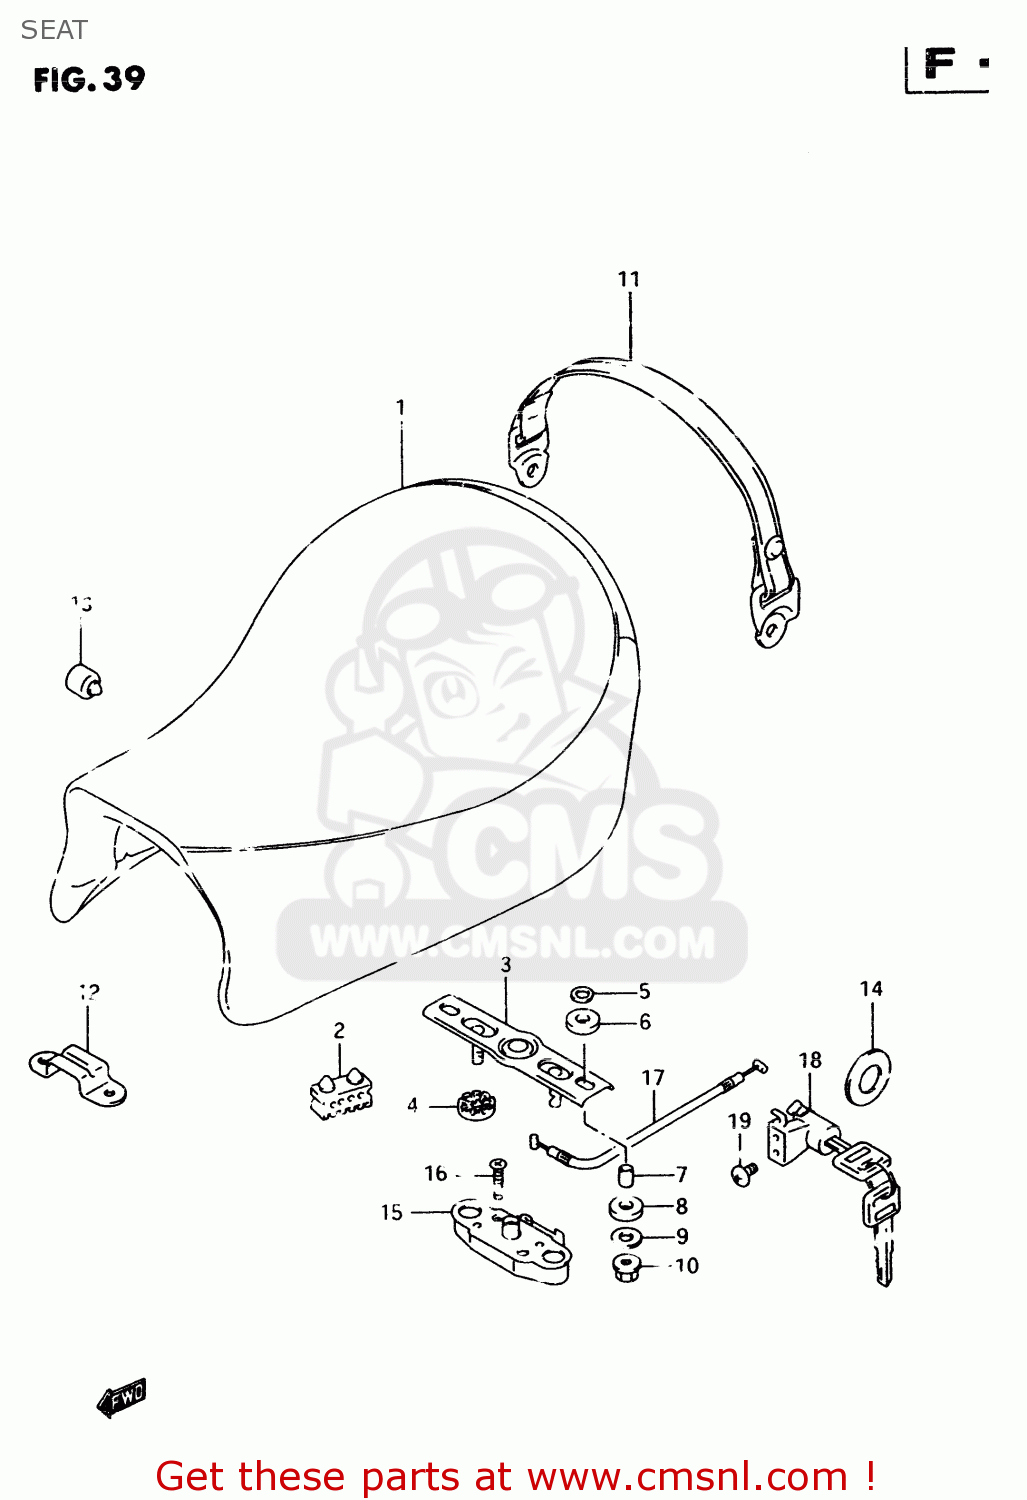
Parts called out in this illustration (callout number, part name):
1	SEAT ASSY(BROWN)
2	CUSHION,SEAT(40X20X15)
3	STRIKER,SEAT LOCK
4	CUSHION,SEAT LOCK(10X22X6)
5	WASHER
6	CUSHION,UPR
7	SPACER(6.1X8X12)
8	CUSHION,LWR
9	WASHER
10	NUT
11	BAND ASSY,SEAT
12	PLATE,SEAT FR HOOK
13	CUSHION
14	COVER,SEAT LOCK,SIDE HOLE
15	BRACKET,SEAT SUPPORT,RIGHT
16	SCREW
17	CABLE, SEAT LOCK
18	LOCK SET,SEAT
19	SCREW
